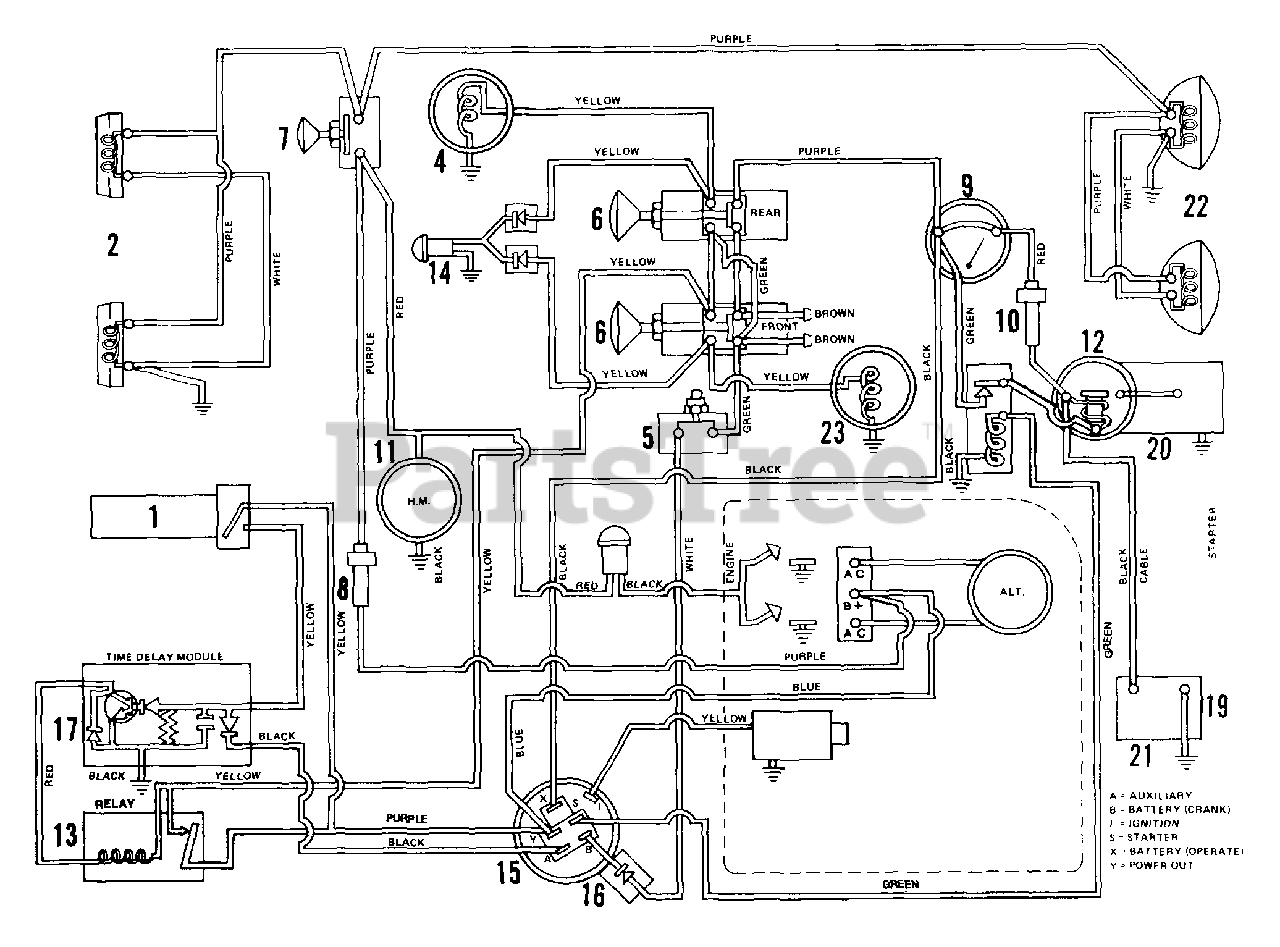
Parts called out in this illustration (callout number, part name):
1	SWITCH SEAT
2	TAIL LIGHT ASSEMBLY W/BULLET
2	TAIL LIGHT LENS
2	MALE DISCONNECT ADAPTER
2	SCR-MCH 10-24X.50 SLTR PL
2	WSHR-LK 10X.047 MED PL
2	NUT-HEX 10-24 PL
4	ELECTRIC CLUTCH
5	SAFETY SWITCH
5	CONNECTOR
5	NUT-HEX .625-32 PL
6	CLUTCH SWITCH
6	CONNECTOR
6	WSHR-FL-STL .382X.812X.023 PL
7	LIGHT SWITCH
7	CONNECTOR
7	WSHR-FL-STL .382X.812X.023 PL
8	7 Amp Fuse
9	AMMETER
9	WSHR-LK-EXT #10 ID X .022
9	NUT 10-32 PL
10	30 Amp Fuse
11	HOUR METER
12	SOLENOID
12	WSHR-LK-EXT #10 ID X .022
12	NUT 10-32 PL
12	WSHR-LK-INT .313X.030 PL
12	NUT-JAM .312-24 PL
12	BLT-HEX .25-20X.75 PL GR2
12	BLT-HEX .25-20X1.00 GR2
12	WSHR-FL-STL.281X.62X.065 PL
12	WSHR-LK-EXT. 250 ID
13	RELAY
14	PTO INDICATOR LIGHT
14	LAMP SOCKET
14	SPEED NUT
15	SWITCH ASSEMBLY
15	CONNECTOR HOUSING
15	WSHR-LK-INT .563X.040 PL
15	NUT .562-24
16	DIODE ASSEMBLY
16	SCR-TAP .250-20X.50 HXSLHDPL
17	TIME DELAY MODULE
17	SCR-MCH 10-24X.50 SLTR PL
17	WSHR-LK 10X.047 MED PL
17	NUT-HEX 10-24 PL
19	GROUND CABLE .25X6.50X.31
19	BATTERY CABLE
19	WSHR-LK .250X.077 HVY PL
19	NUT-HEX .250-20 PL
20	STARTER CABLE .25X.35.25X.31
20	GROUND CABLE
21	BATTERY
22	HEAD LIGHT
22	HEAD LIGHT RETAINER RING
22	SCR-MCH 10-24X.50 SLTR PL
22	WSHR-FL-STL .250X.562X.049 PL
23	DIESEL CLUTCH ASSEMBLY
23	CLUTCH ASSEMBLY 1 1/8 BORE
23	CLUTCH ASSEMBLY 1-1/4 BORE
27	CONNECTOR
